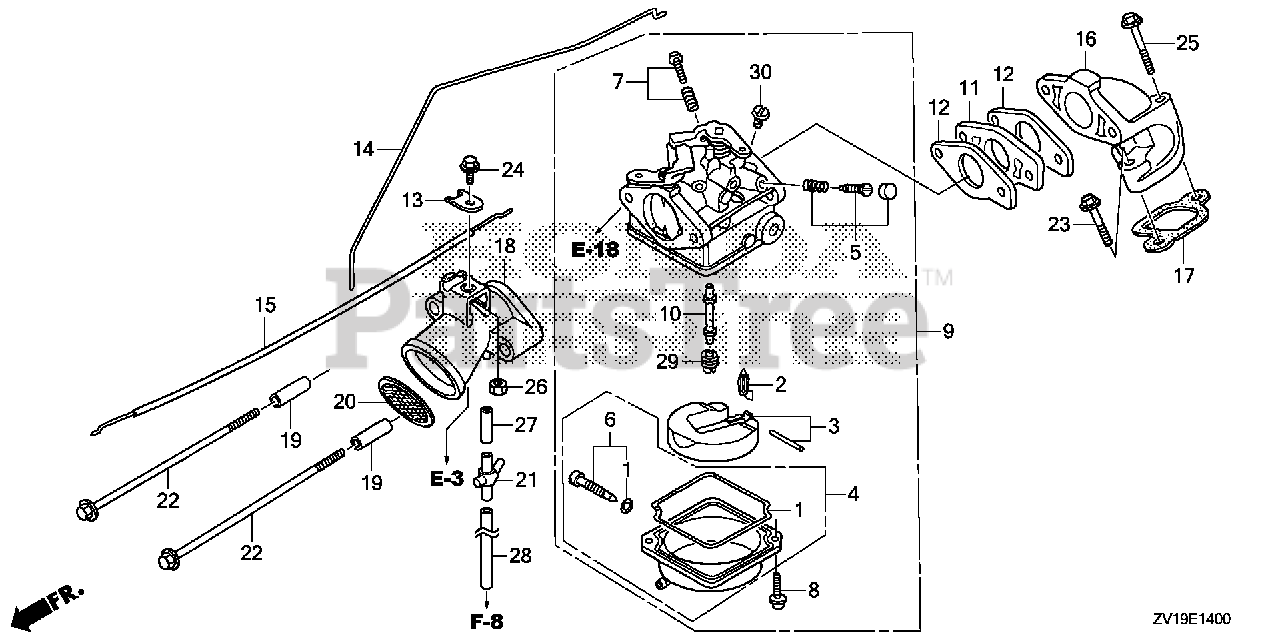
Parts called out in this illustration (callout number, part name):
1	GASKET SET
2	VALVE SET, FLOAT
4	CHAMBER SET, FLOAT
5	SCREW SET (CARBURETOR NO.)
6	SCREW SET, DRAIN (CARBURETOR NO.)
8	SCREW, PAN
9	CARBURETOR ASSY. (BC05E D)
11	INSULATOR, CARBURETOR
12	GASKET, CARBURETOR
13	HOLDER, CABLE
14	ROD, THROTTLE
15	CABLE, CHOKE
16	MANIFOLD, IN.
17	GASKET, IN. MANIFOLD
18	GUIDE, AIR
19	COLLAR, DISTANCE
20	TRAP, FLAME
21	JOINT, THREE WAY
22	BOLT, FLANGE (6X102)
23	BOLT, FLANGE (6X28) (CT200)
24	BOLT, FLANGE (6X12)
25	BOLT, FLANGE (6X42)
26	NUT, HEX. (6MM)
27	BULK HOSE, VINYL (4X7X8000) (95003-07(95003-07001-60M) (CARBURETOR NO.)
28	BULK HOSE, VINYL (4X7X8000) (95003-07(95003-07001-60M) (CARBURETOR NO.)
29	JET, MAIN (#68) (CARBURETOR NO.)
29	JET, MAIN (#70) (CARBURETOR NO.)
29	JET, MAIN (#75) (CARBURETOR NO.)
